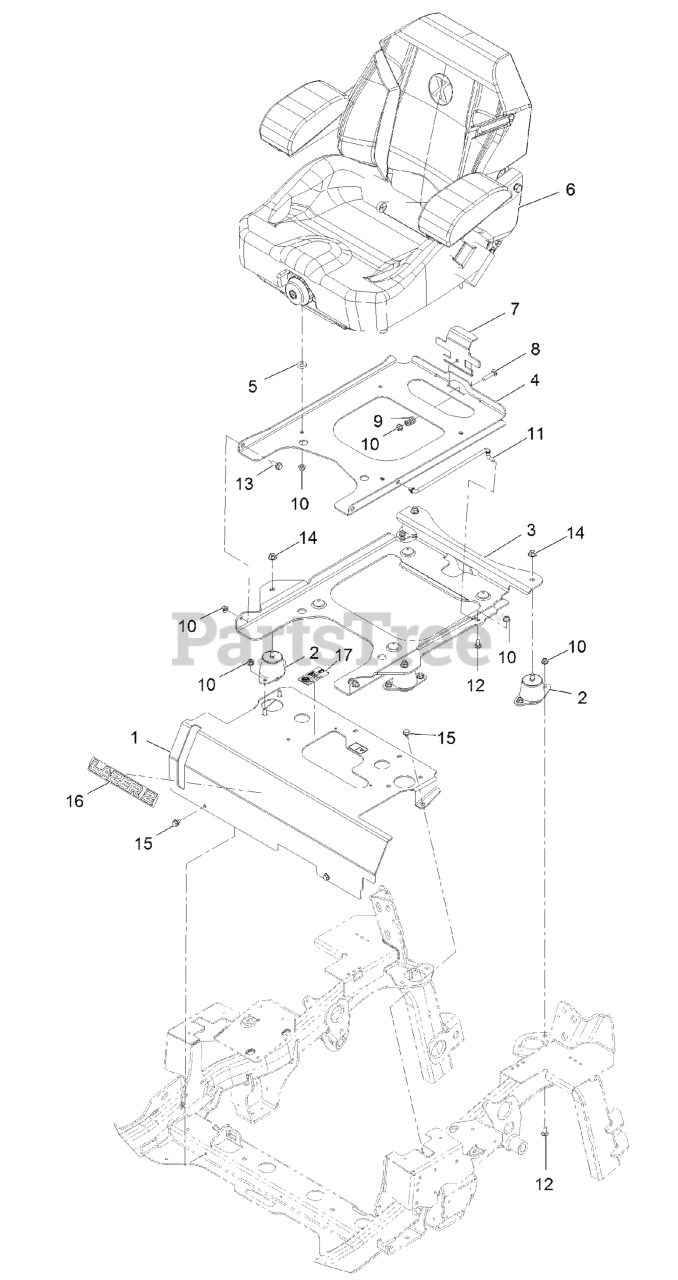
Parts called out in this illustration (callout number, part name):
1	SEAT MOUNT ASM
2	ISOLATOR-SEAT
3	PLATE-SUPPORT, TILT SEAT
4	PLATE-FRAME, SEAT
6	KIT-SUSPENSION SEAT
7	PLATE, SEAT LATCH
8	BOLT-CARR
9	SPRING-COMPRESSION
10	NUT-HF, NI
11	ROD-PROP
12	SCREW-CARR
13	SCREW-SHOULDER
14	NUT-HF, NI
16	DECAL, LAZER MODEL
17	DECAL-TRANS FLUID
